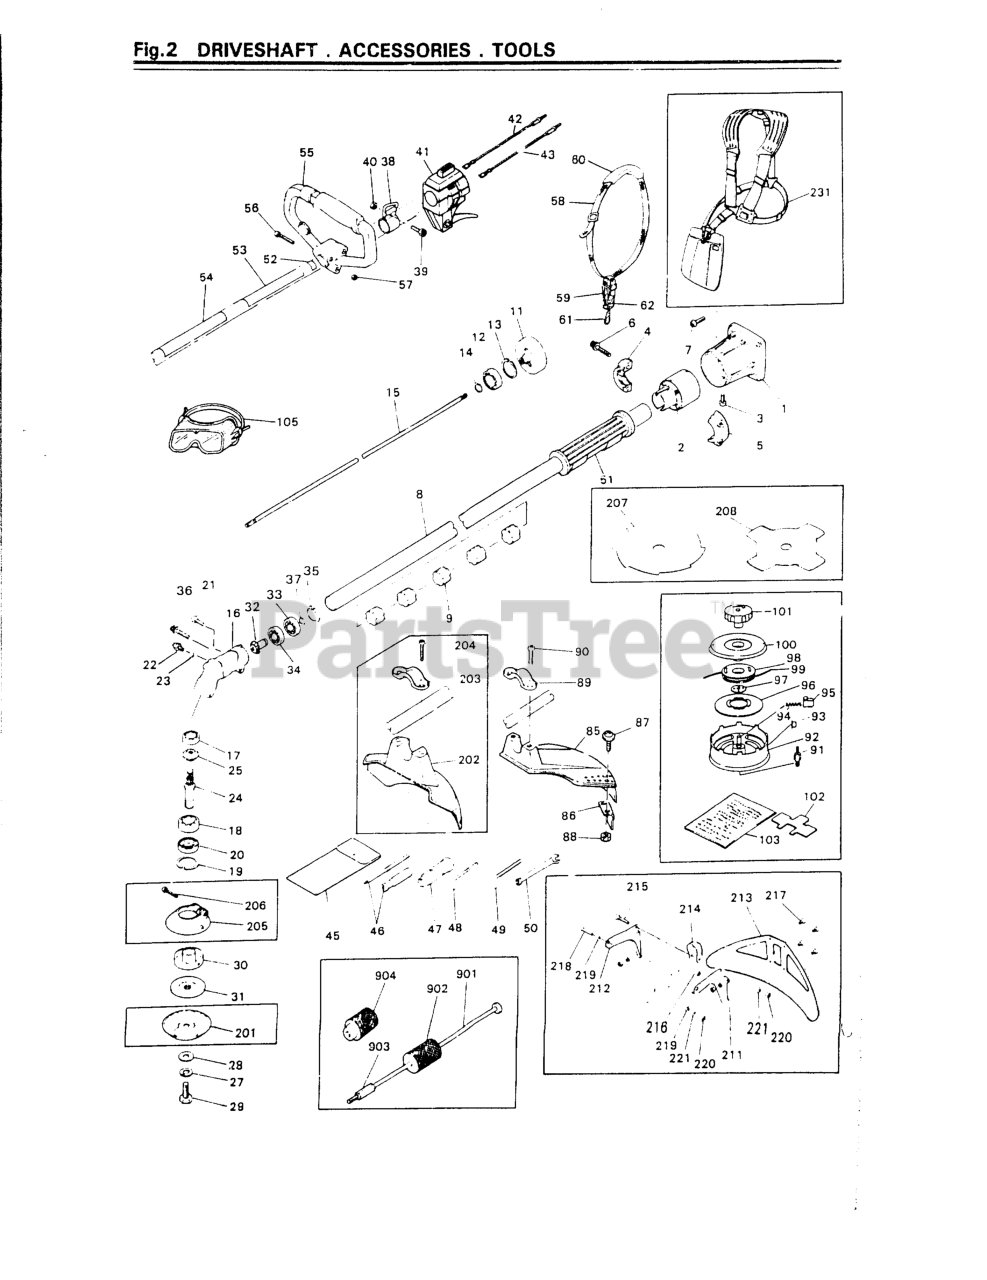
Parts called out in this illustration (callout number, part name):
3	SCREW, M6 x 10
5	CLAMP (L)
6	BOLT
7	BOLT, M6 X 20
11	DRUM CLUTCH (USE 6460-12112)
12	BEARING
13	RING, SNAP, M28 x 1.2
18	BEARING
19	RING, SNAP, M28 x 1.2
20	SEAL, OIL
21	BOLT, M5 X 10
22	FITTING, GREASE
23	WASHER, M6 X .8
25	GEAR, BEVEL (NLA)
27	WASHER (RPLS 3180-13270)
28	WASHER, M8 x 2.3 (RPLS -20823)
29	BOLT, LH
30	HOLDER (NLA)
31	HOLDER (B)
32	PINION (NLA)
33	BEARING (RPLS T3300-13531)
34	BEARING (RPLS T3403-13530)
35	RING, SNAP, M24 x 1.2
36	BOLT
37	RING, SNAP (RPLS T3300-13330)
38	HANGER COMP
39	BOLT, M5 X 10
40	NUT, M5 X 4
42	CORD-A, BLACK
43	CORD-B, RED
46	SCREWDRIVER
48	WRENCH (TOOL)
49	BAR
50	SPANNER, 8 X 10 (RPLS 2540- )
52	LABEL, POSITIONING
53	PLATE, NAME
55	HANDLE ASSEMBLY (NLA)
56	SCREW, M5 x 30(RPLS 0263-00530
57	NUT, M5 X 4
86	BLADE
87	SCREW, M5 x 12
89	CLAMP (REPLACES 5807-24120)
90	BOLT, M6 x 1.30
91	ADAPTER-MALE
92	HOUSING, SPOOL
93	EYELET (RPLS -15220)
94	SPRING, RED
94	SPRING, WHITE
94	SPRING, SILVER
94	SPRING, CAM
95	SLIDE CAM (1 PC)
96	CAM DISK
97	NUT, FLAT
102	FASTENING TOOL
201	COVER (REPLACES D0041) ACC.
202	GUARD (USE 3520-24112)
203	CLAMP (REPLACES 5807-24120)
204	BOLT, M6 x 1.30
206	SCREW, M5 X 30
211	BRACKET (A)
213	GUARD (NLA)
214	CLAMP (NO LONGER AVAILABLE)
215	BOLT, M5 X 30
219	WASHER, M5x.8(RPLS 01624-20508
220	NUT, M5 X 4
221	WASHER, SPRING M4 x 1.3
231	HARNESS ASSEMBLY
901	SHAFT (TOOL)
903	ADAPTER (B) (TOOL)
904	BLOCK (TOOL)
